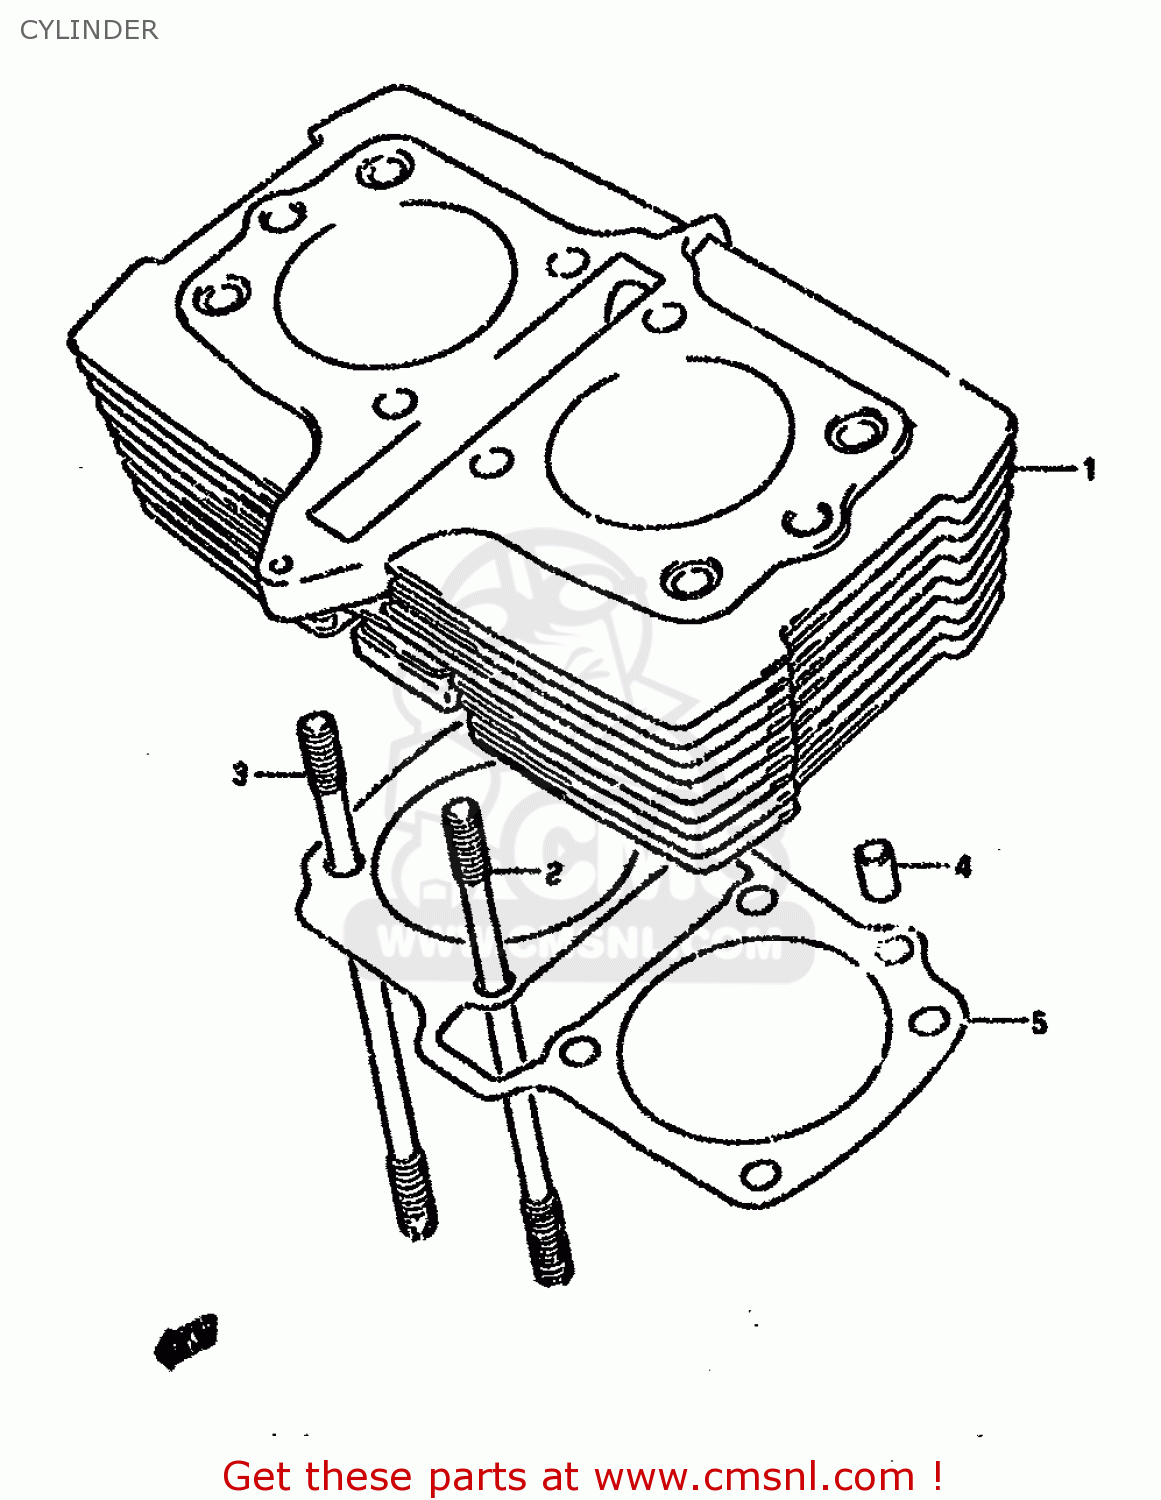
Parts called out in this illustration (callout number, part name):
1	CYLINDER
2	BOLT,STUD
3	STUD
4	PIN
5	GASKET,CYLINDER (NAS)
